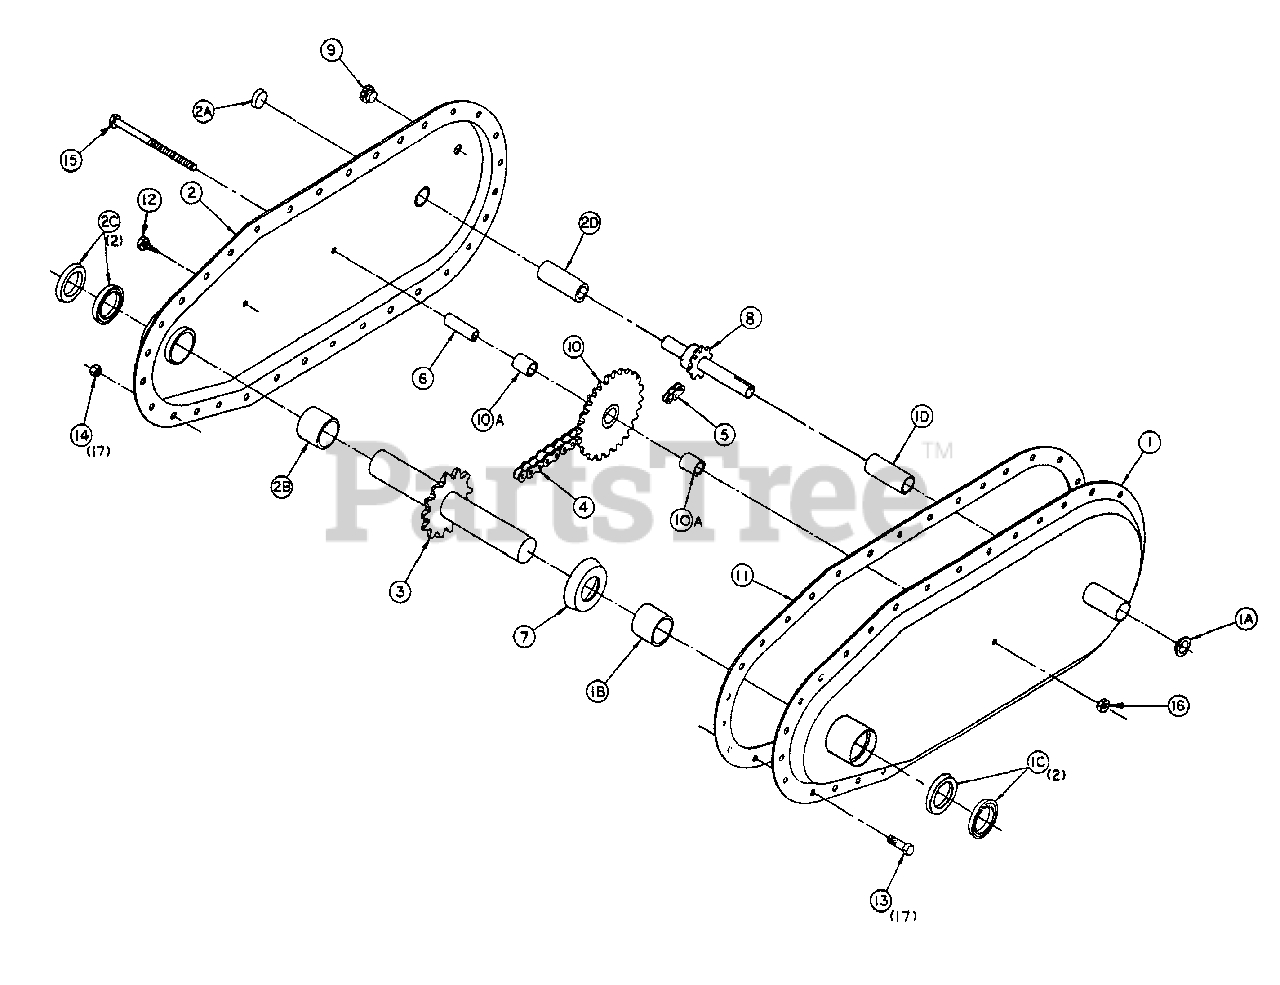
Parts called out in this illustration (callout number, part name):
1	L.H. Case Half Assembly
1A	Drive Shaft Seal
1B	Tine Shaft Bearing
1C	Tine Shaft Seal
1D	Bearing
2	R.H. Case Half Assembly
2A	Soft Plug
2B	Tine Shaft Bearing
2C	Tine Shaft Seal
2D	Bearing
3	Tine Assembly Shaft
4	Roller Chain #50-40 Pitches
5	Roller Chain #35-50 Pitches
6	Idler Sprocket Inner Race
7	Tine Shaft Spacer
8	Drive Shaft Assembly
9	Oil Plug
10	Idler Sprocket Assembly
10A	Idler Sprocket Bearing
11	Transmission Case Gasket
12	1/4 x 3/4" Self Tapping Screw
13	1/4-20 x 1/2" HH Whiz Lockscrew
14	1/4-20 Whiz Locknut
15	5/16-18 x 2-3/4" HHCS
16	5/16-18 Nylok Locknut
